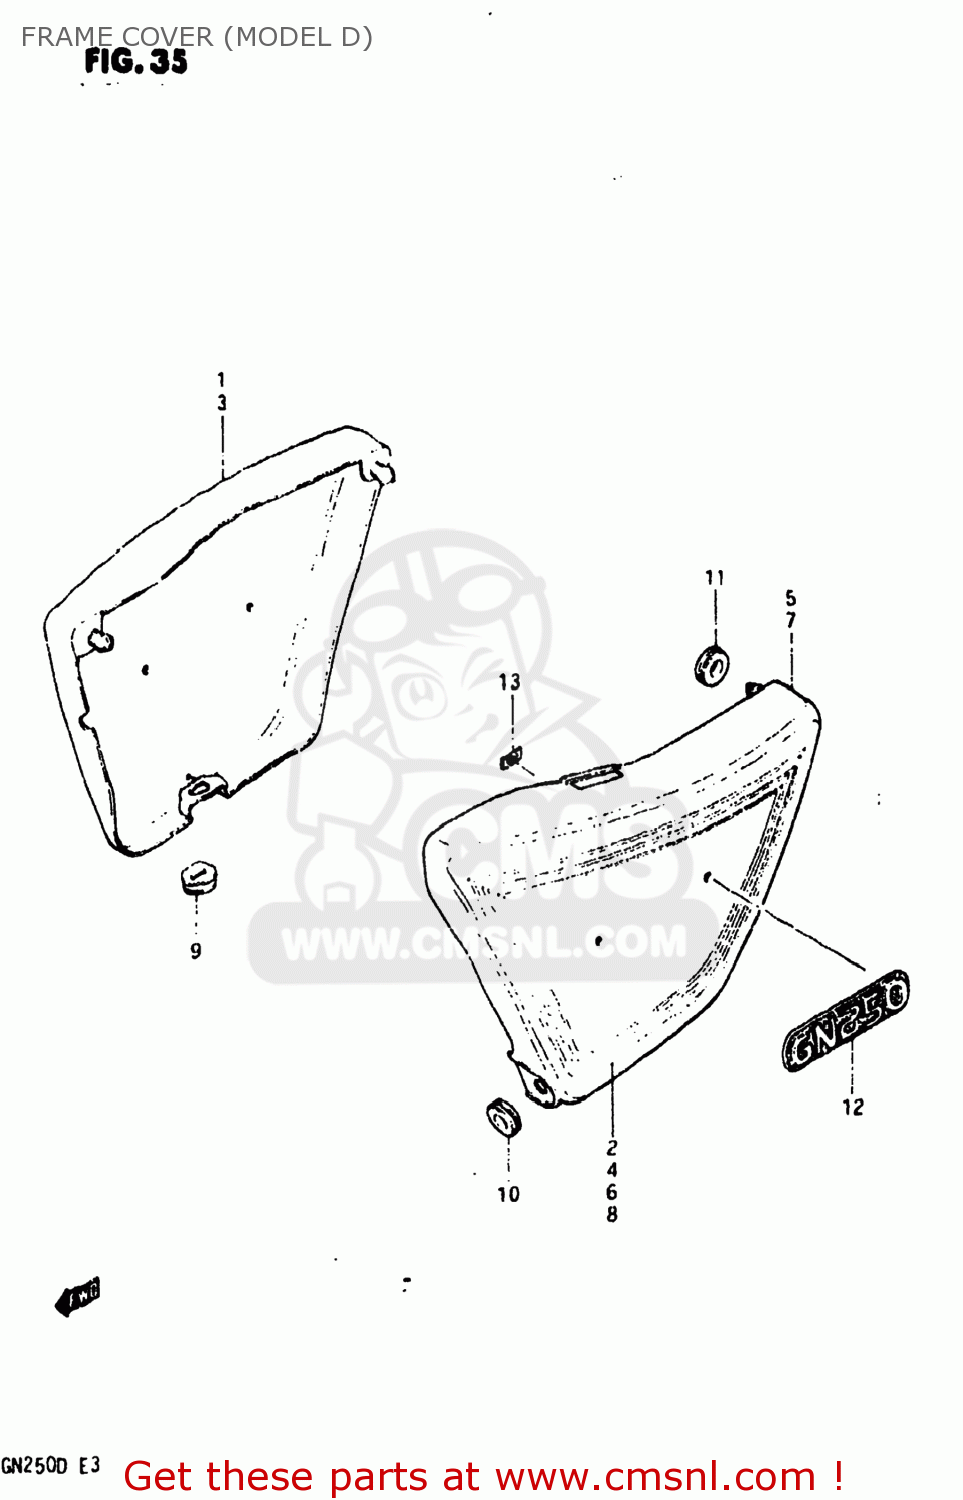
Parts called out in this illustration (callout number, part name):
1	COVER,FRAME,RIGHT
2	TAPE SET,FRAME COVER,R
3	COVER,FRAME,RIGHT
4	TAPE SET,FRAME COVER
5	COVER,FRAME,L(RED)
6	TAPE SET,FRAME COVER,L
7	COVER,FRAME,LEFT
8	TAPE SET,FRAME COVER
9	CUSHION
10	CUSHION
11	CUSHION
12	EMBLEM,GN250
13	NUT
